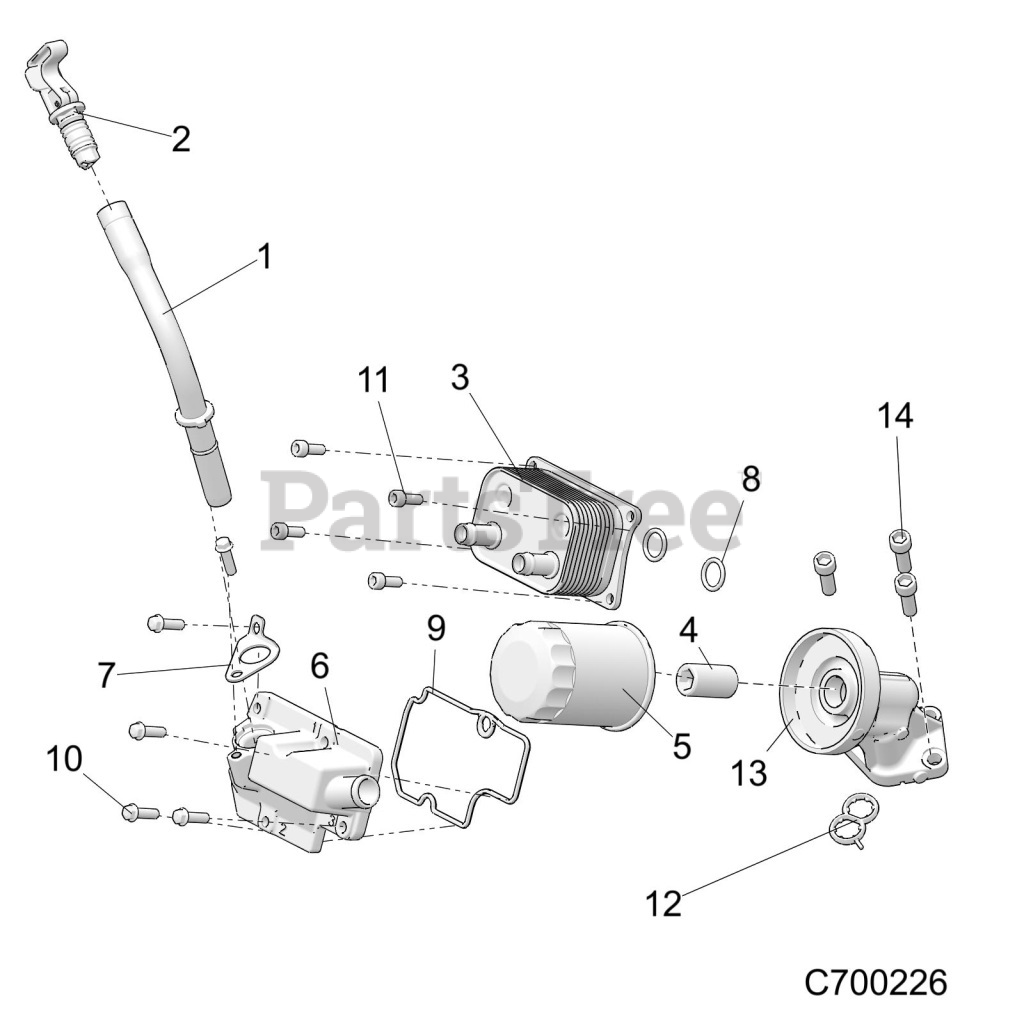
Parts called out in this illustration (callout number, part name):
1	ASM-OIL FILL TUBE
1	O-RING 12MMX2MM
2	ASM-DIPSTICK
3	COOLER-OIL TO WATER,5
4	ADAPTOR, FILTER, STRAIGHT
5	FILTER-OIL,10 MICRON,(12)
6	COVER-BREATHER,MACH
7	BRACKET-TUBE,OIL FILL,LOWER
8	O-RING,.612X.818X.103
9	SEAL-COVER,BREATHER
10	SCR-M6X20,HXFLG,0600214
11	SCR-SH-M6X1.0X16 8.8 ZPY D204
12	SEAL-FILTER ADAPTER-3HOLE
13	ADAPTER-OIL FILTER,MACH
14	SCR-SH-M8X1.25X25 8.8 ZPC NYL
